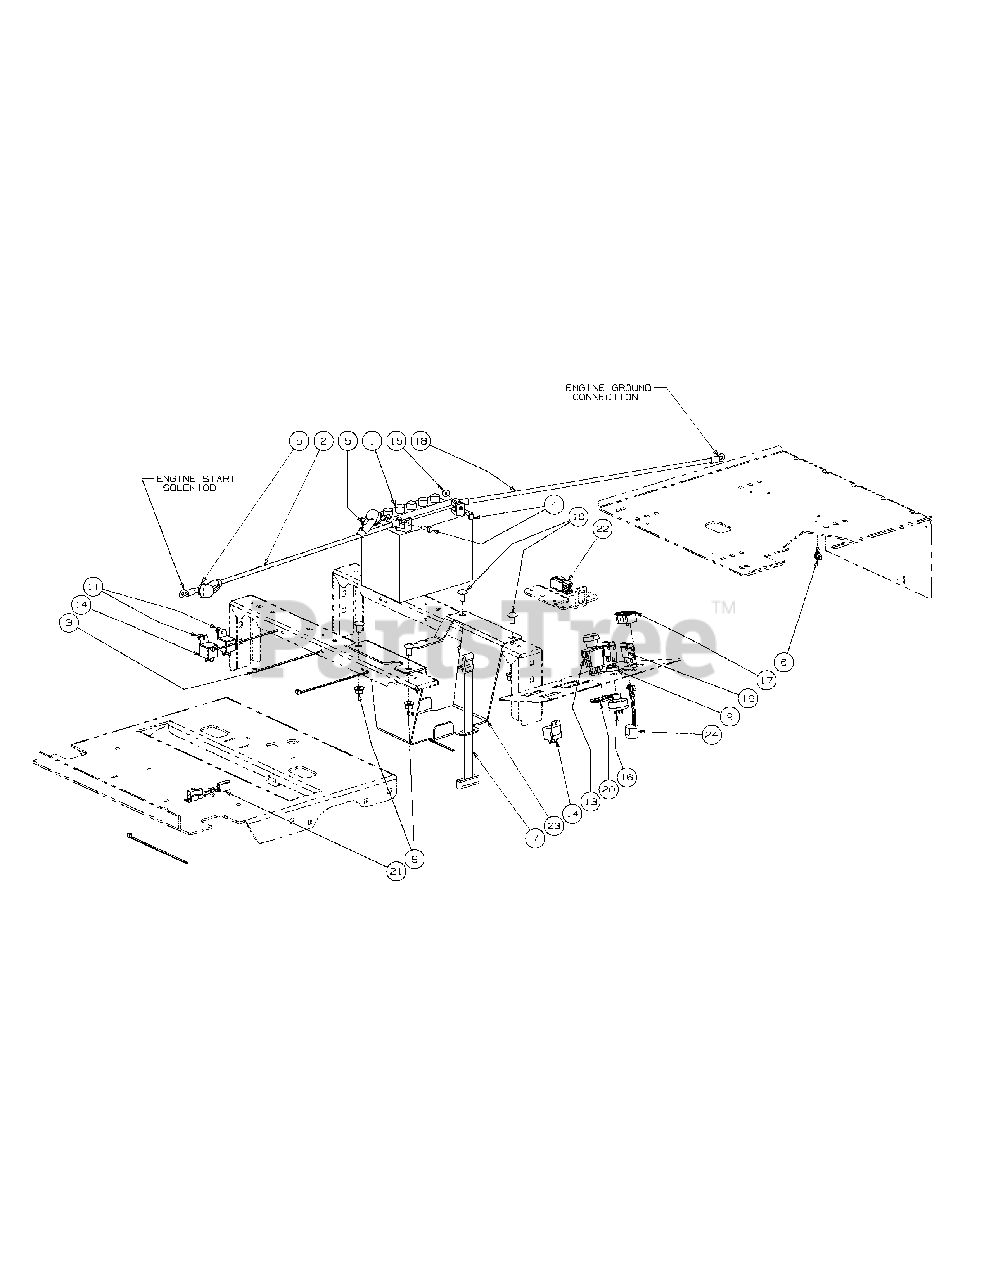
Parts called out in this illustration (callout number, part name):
1	Battery, 12V 225CCA 30 Min
2	Cable, Battery, Red, 36"
3	Tie, Cable, 3/16 x .05 x 7.4"
4	Screw, Hex, Cap, 1/4-20 x .75
5	Boot, 1" OD Rubber Battery-PST, Red
6	Electrical Conduit Clip, 3/8
7	Strap, Battery
8	Flange Lock, Hex Nut, 3/8-16
9	Nut, W/Cap, 5/8-32 Ignition
10	Carriage Bolt, 3/8-16 x .75 Long
11	Self Tapping Screw, 1/4-20 x .50
13	Switch, Electric, PTO
14	Relay, 12V 40A
15	Hex Flange Lock Nut, 1/4-20
16	Switch, Ignition, 6 Pin
17	Meter, Hour includes:
18	Cable, Battery Black, 34"
19	Light Indicator, 12V
20	Bracket, PTO Switch Retainer
22	Neutral Switch
23	Battery Bracket
24	Alarm, High Temp
